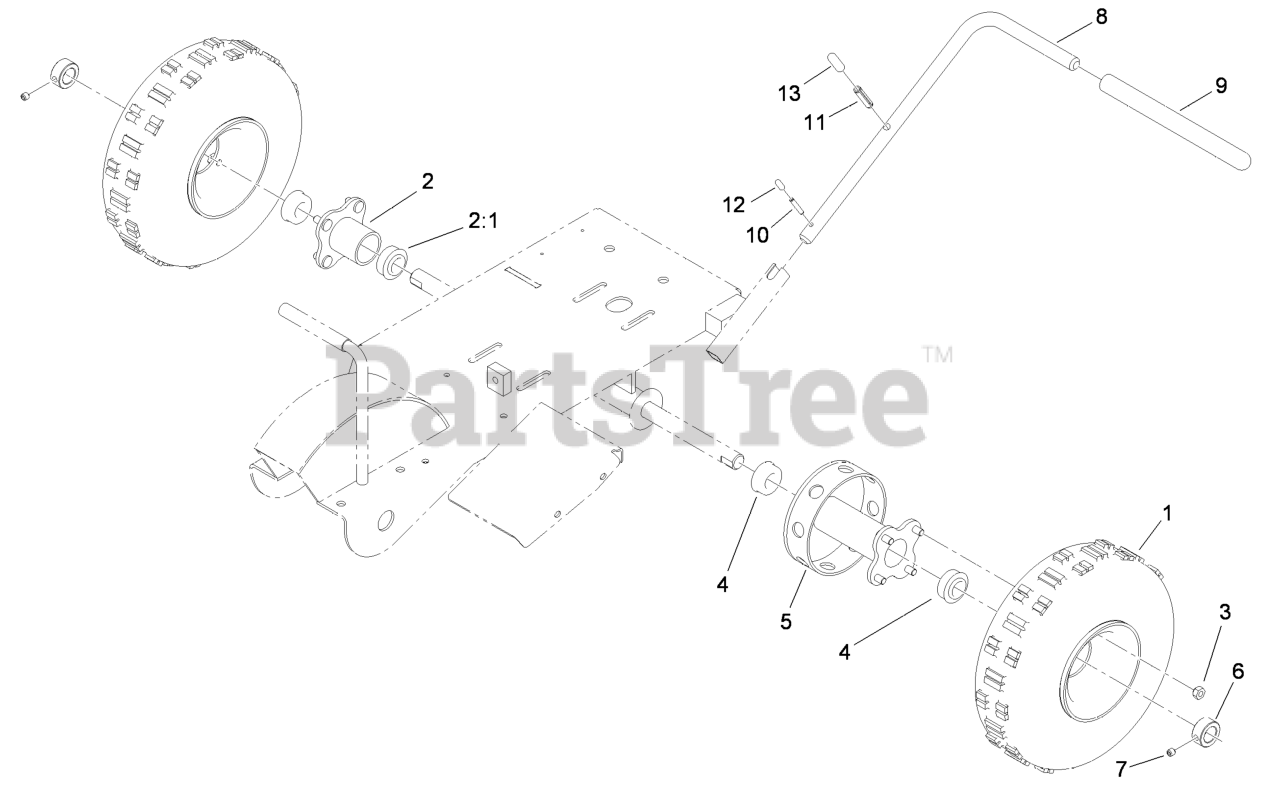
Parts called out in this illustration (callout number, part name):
1	WHEEL AND TIRE ASM
2:1	BEARING-WHEEL
3	NUT-WHEEL
4	BEARING-WHEEL
5	HUB-BRAKE
6	COLLAR-SET
7	SCREW-SET, HSH
8	HANDLE-BRAKE
10	PIN-ROLL, SLOTTED
11	PIN-ROLL
12	CAP-LOWER
13	CAP-UPPER
